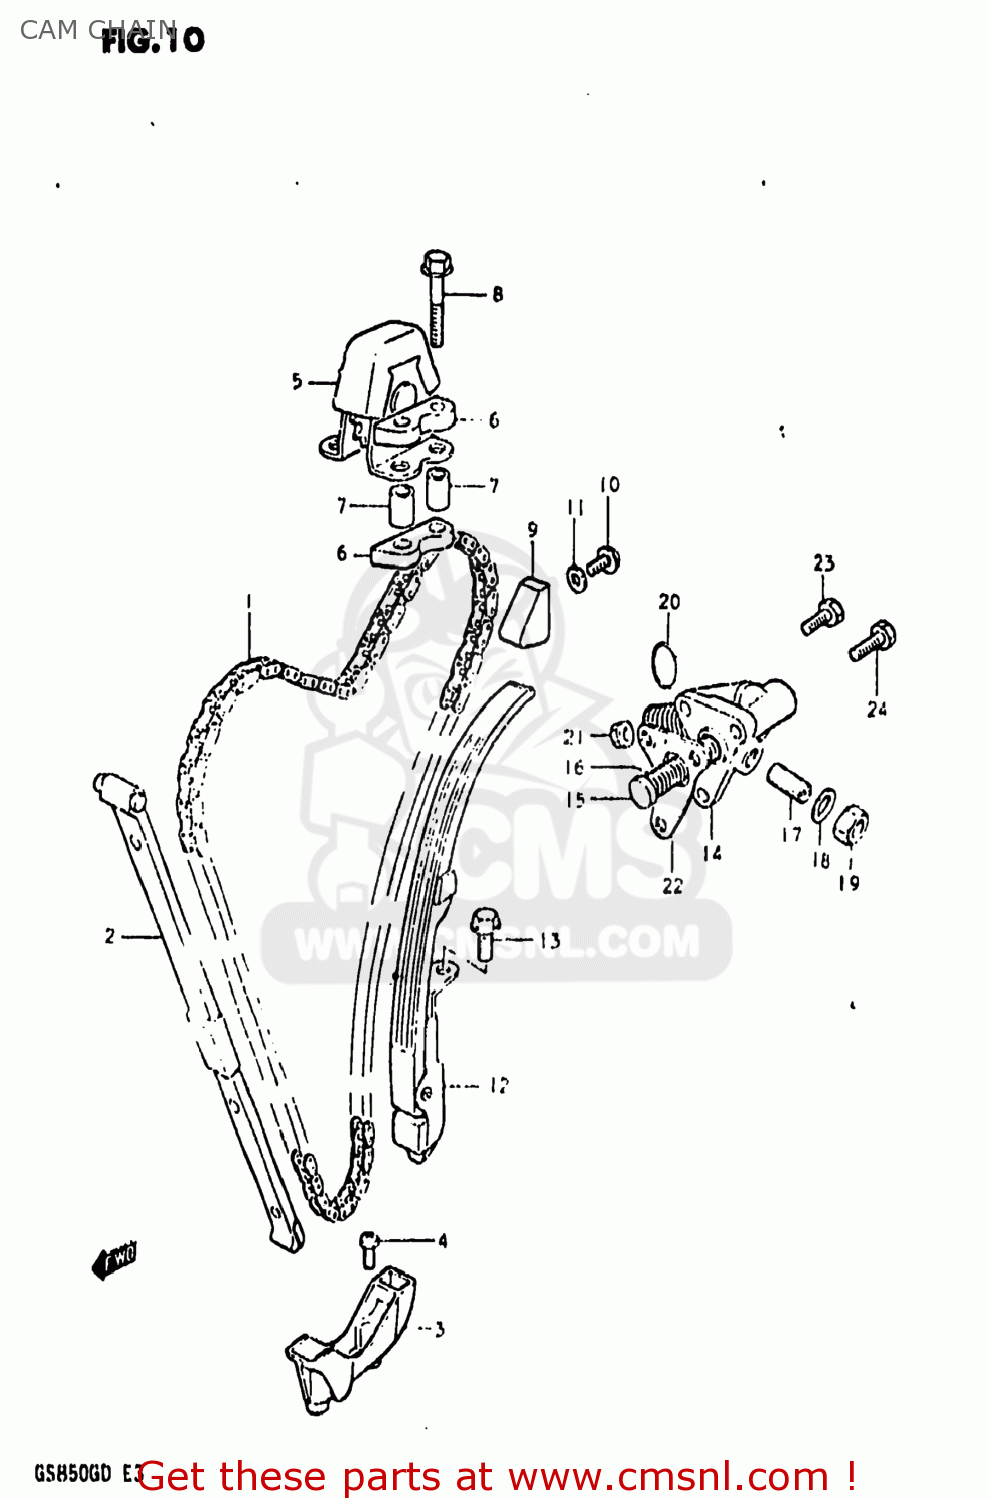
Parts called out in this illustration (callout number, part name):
1	CHAIN,CAMSHAFT DRIVE(120L)
2	GUIDE,CAM CHAIN NO.1
3	HOLDER,CAM CHAIN GUIDE
4	SCREW
5	IDLER,CAM CHAIN
6	CUSHION,IDLER
7	SPACER
8	BOLT
9	GUIDE,CAM CHAIN
10	BOLT
11	GASKET (NAS)
12	TENSIONER,CAM CHAIN
13	BOLT
14	ADJUSTER ASSEMBLY,TENSIONER
15	ROD,PUSH
16	SPRING
17	SCREW
18	WASHER
19	NUT
20	O-RING
21	NUT
22	GASKET,TENSIONER ADJUSTER (MCA)
23	SCREW (6X25)
24	SCREW
